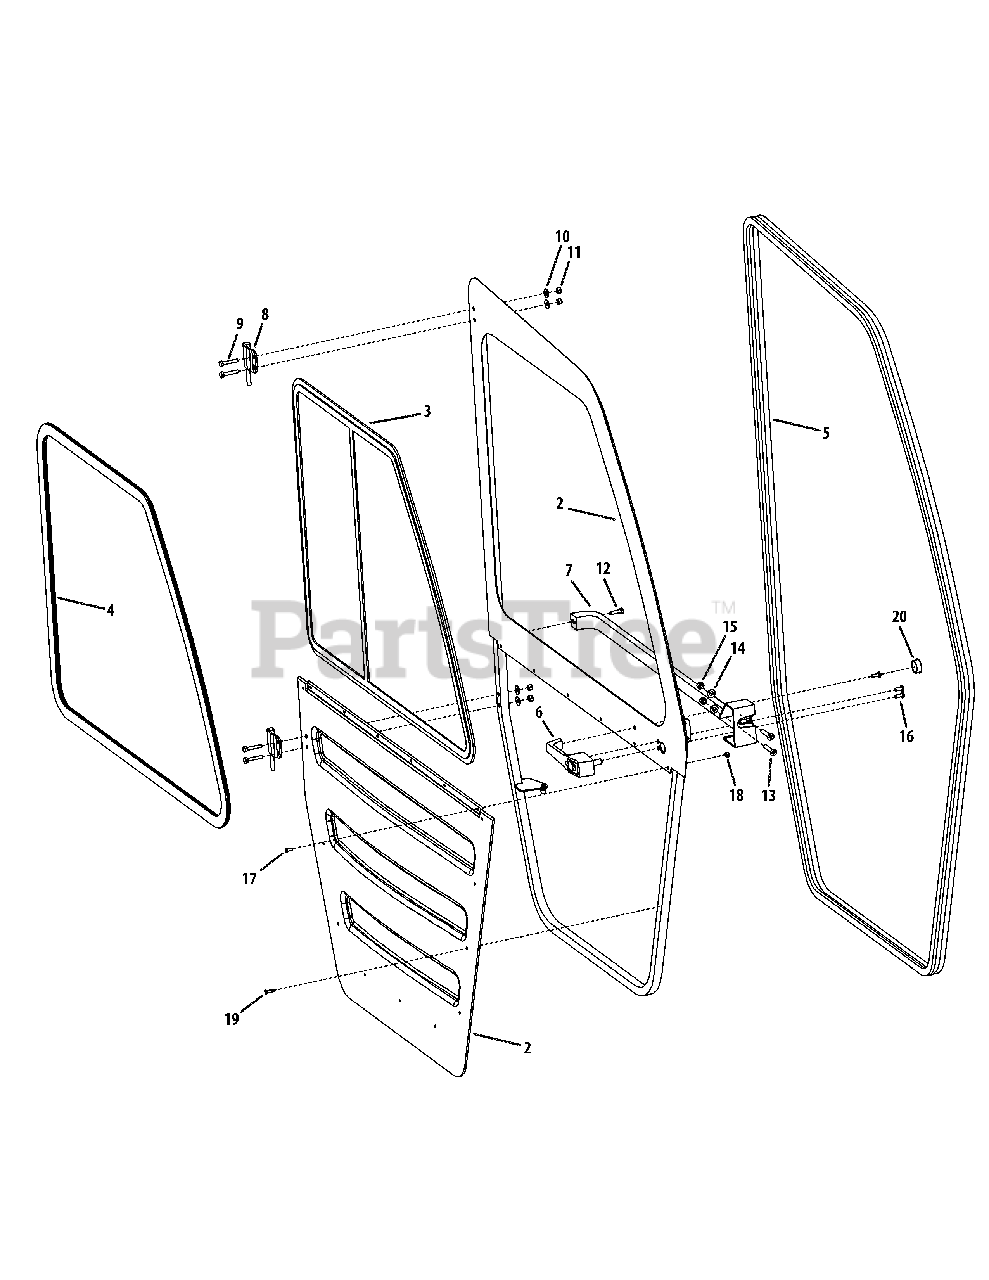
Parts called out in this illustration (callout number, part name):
2	Door Frame with lower Panel, RH
3	Sliding Window, Temp. Glass
4	Window Mounting Rubber - 10’
5	1-1/2" Side Bulb & 2 Wipers - 15’
6	Outside Handle (Set Of 2)
7	Door Latch RH - Non Locking
8	Tube Frame Hinge, RH
9	Hex Bolt, 1/4-20 x 1 1/2"
10	Washer, 1/4"
11	Locknut, 1/4-20
12	Hex Bolt, 1/4-20 x 3/4"
13	Hex Bolt, 5/16-18 x 1 1/2"
14	Washer, 5/16
15	Locknut, 5/16-18
16	Hex Bolt, M6 x 12mm
17	Hex Bolt, 10-32 x 1/2"
18	Locknut, 10-32
19	Screw, #10 x 3/4"
20	Hole Plug, 1"
